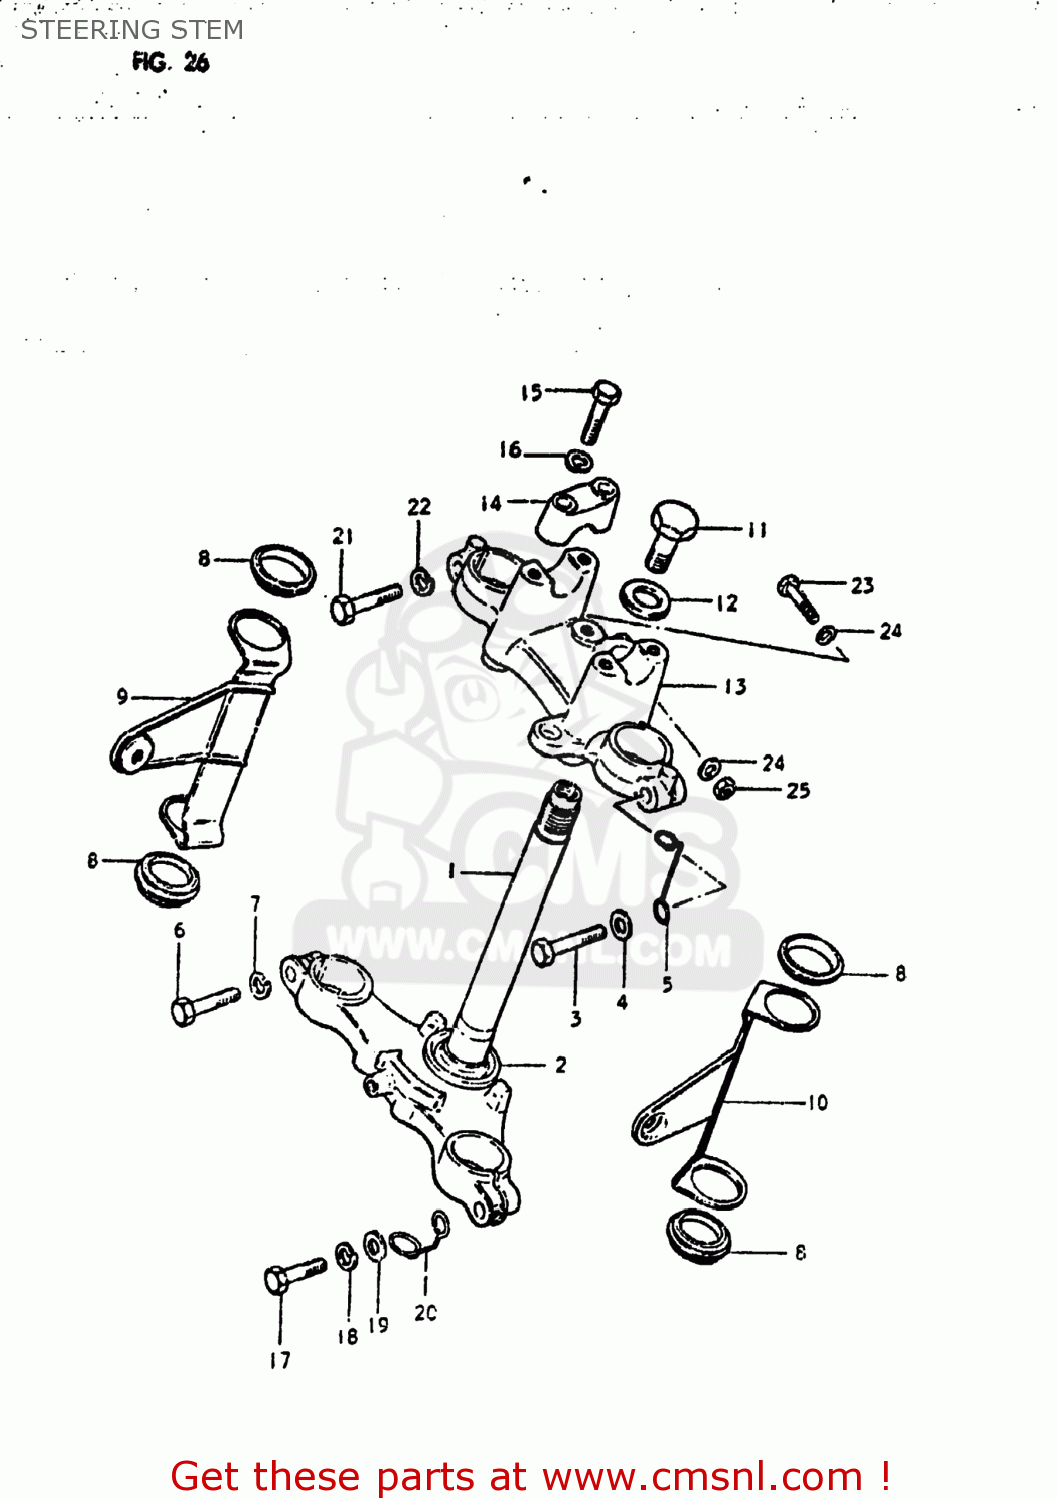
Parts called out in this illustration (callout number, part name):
1	STEM,STEERING
2	RACE,STEERING OUTER LWR
3	BOLT 10X40
4	WASHER
5	GUIDE,CABLE
6	BOLT
7	WASHER,LOCK 12
8	CUSHION,HEADLAMP BRACKET
9	BRACKET,HEADLAMP HOUSING
10	BRACKET,HEADLAMP,LEFT
11	BOLT,STEERING STEM HEAD
12	WASHER
13	HEAD,STEERING STEM
14	HOLDER,HANDLE(BLACK)
15	BOLT
16	LOCK WASHER
17	BOLT
18	WASHER,LOCK 12
19	WASHER
20	CLIP
21	BOLT 10X40
22	LOCK WASHER
23	BOLT 8X55
24	WASHER
25	NUT
